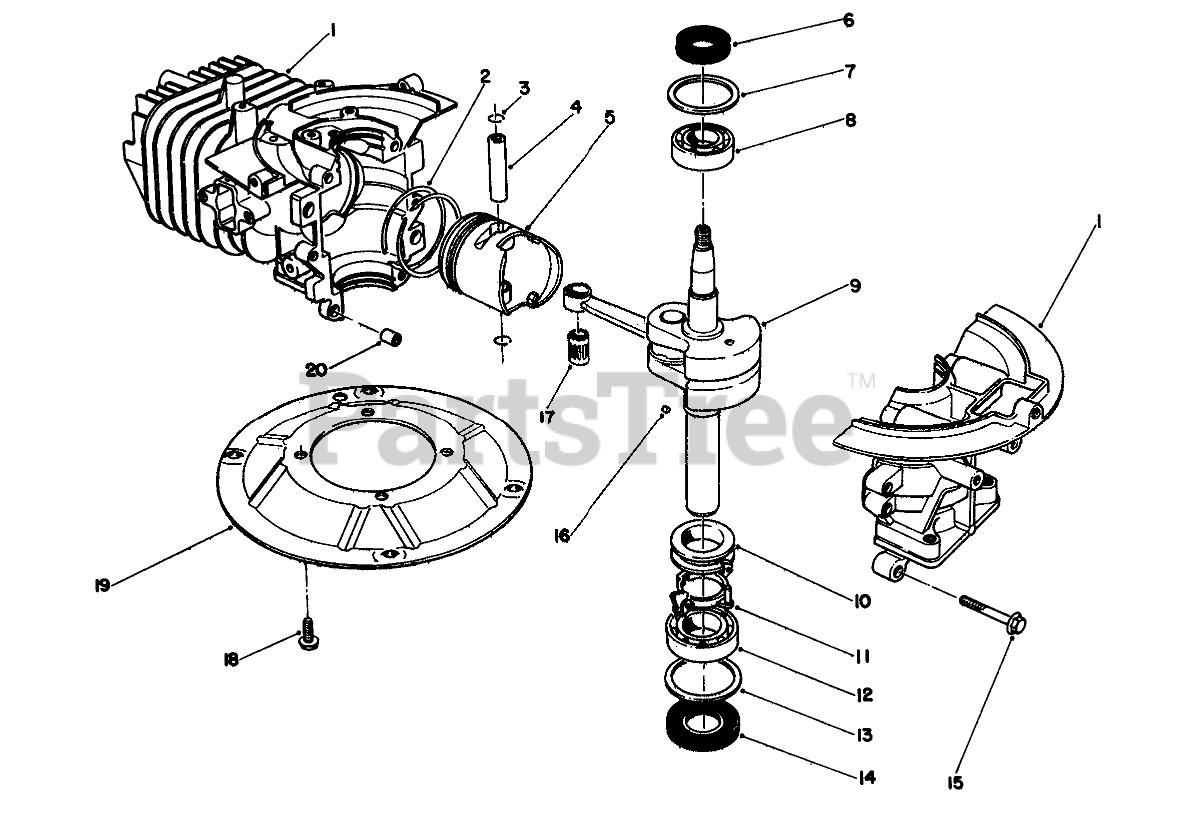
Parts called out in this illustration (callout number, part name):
1	CRANKCASE
2	RING SET
4	PIN-PISTON
5	PISTON
6	OIL SEAL
7	WASHER-UPPER
8	BEARING-UPPER
9	CRANKSHAFT
10	SPACER
11	BRACKET
12	LOWER BRG
13	WASHER-LOWER
14	SEAL-OIL
17	BEARING
19	PLATE-MOUNTING
